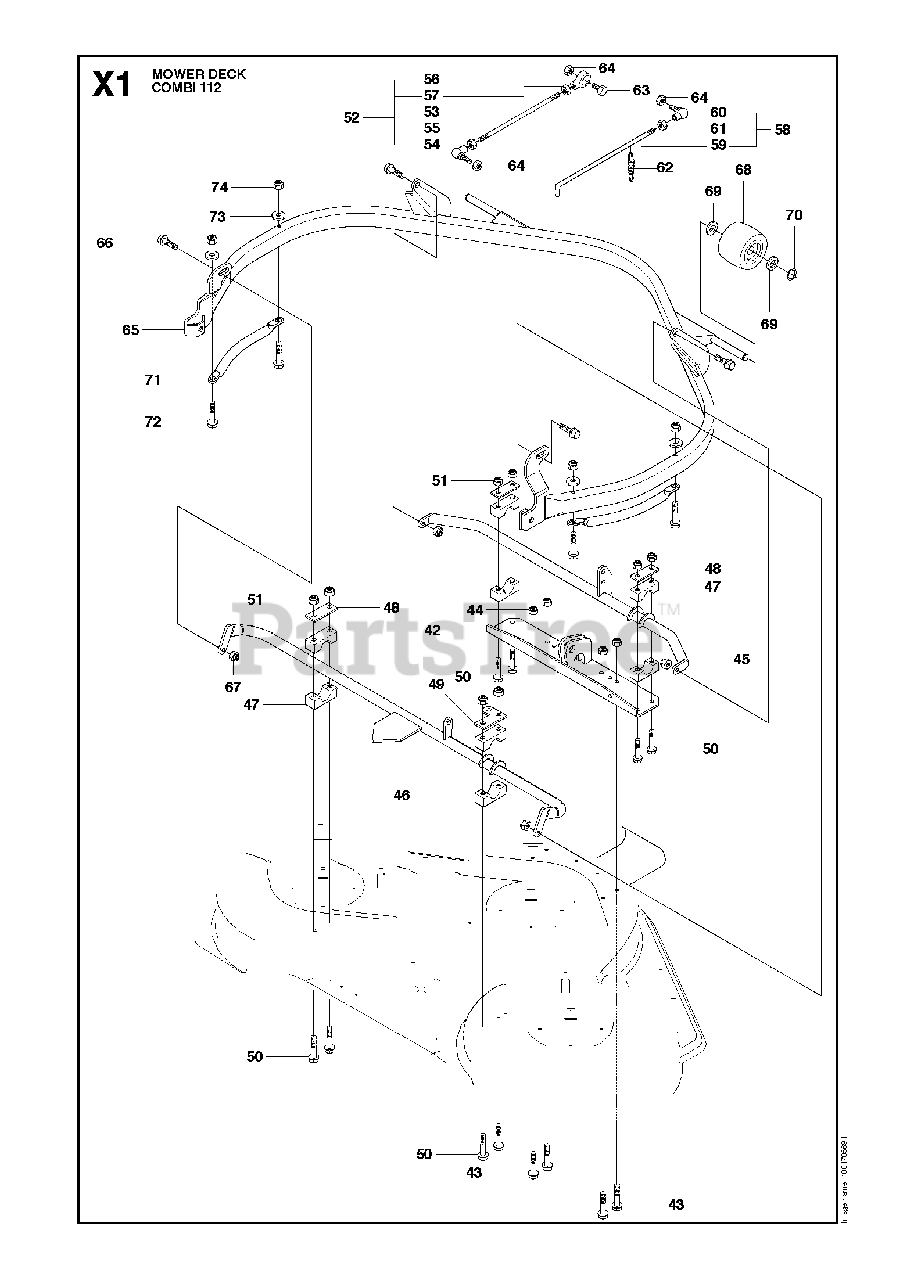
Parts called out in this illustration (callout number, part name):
3	NUT
4	PLUG
5	BOLT
6	RP SPINDLE ASSY
7	SHAFT
8	BEARING
9	SPACER
10	BEARING HOUSING
11	RP SPINDLE ASSY
12	SHAFT
13	BEARING
14	SPACER
15	BEARING HOUSING
17	WASHER BRB 8.4X17
18	LOCKNUT M8
26	BLADE
29	BELT TENSIONER ASSY
30	BELT TENSIONING ARM
31	PULLEY
32	SPACER
33	BOLT
34	WASHER
36	LOCKNUT M8
38	BELT
44	LOCKNUT M8
51	LOCKNUT M8
52	PARALLEL RODY ASSY
53	ROD
54	LINK
56	LINK
57	NUT
58	CLUTCH ROD ASSY
59	ROD
60	LINK
61	NUT
67	LOCKNUT M8
68	DECK ROLLER, FRONT
70	RETAINING RING SGA 15
73	WASHER
74	LOCKNUT M6
